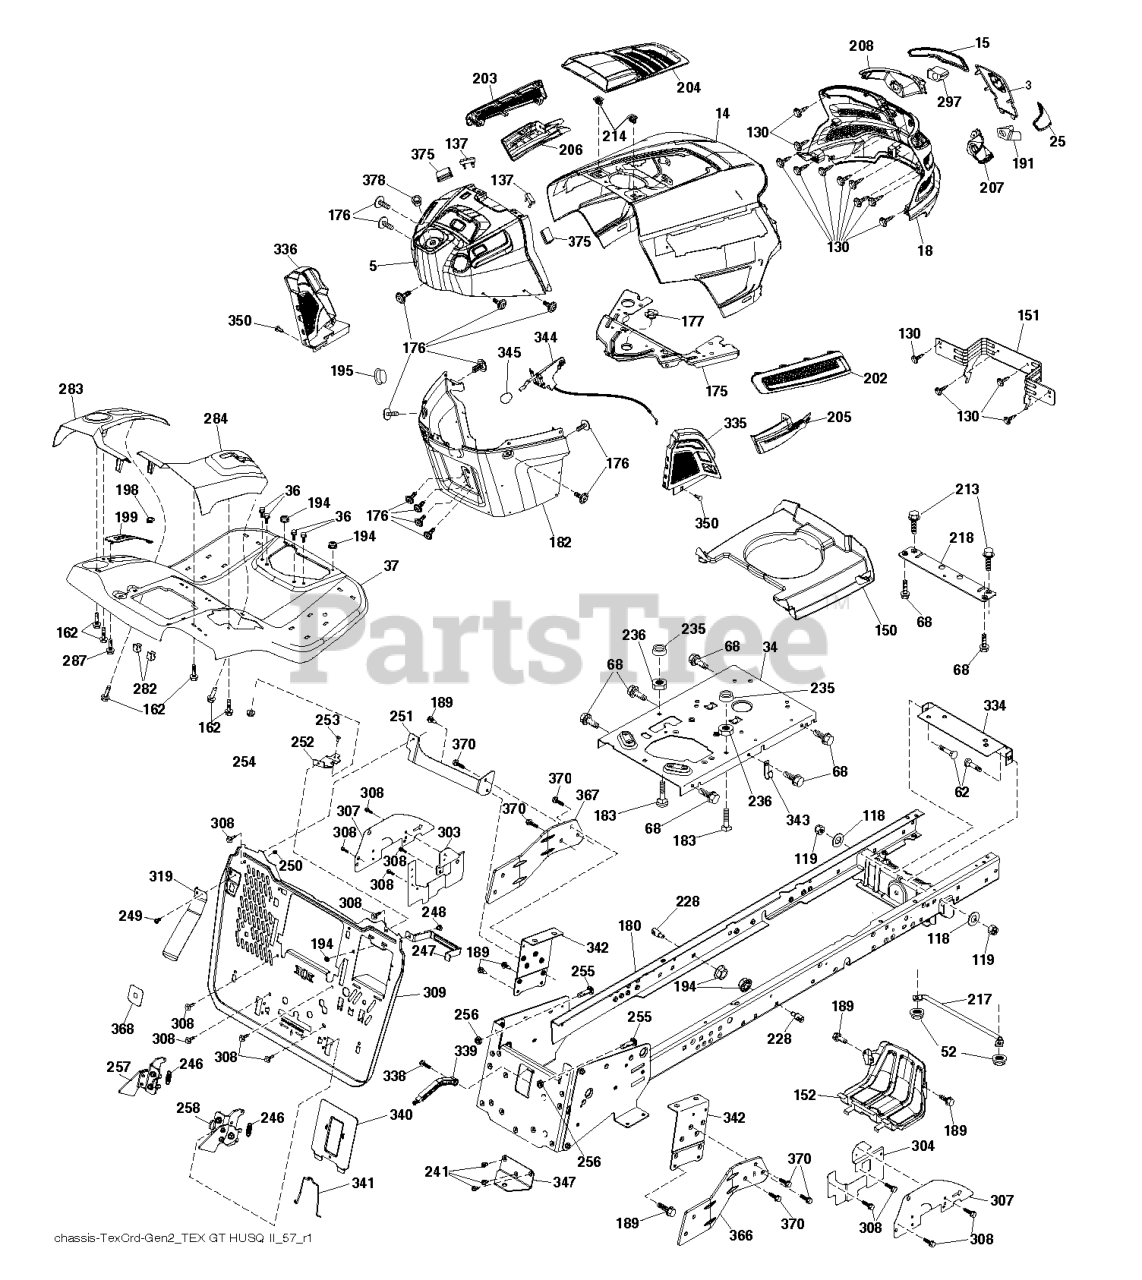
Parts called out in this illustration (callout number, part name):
3	APPLIQUE.SUBASM.GT.HUSQ.II
14	HOOD.ASM.HUSQVARNA.GT.TEX.ORAN
15	LENS.HEADLIGHT.LH.GTII.2011
18	GRILLE SUBASM.GT.II.LOW.HDLGHT
25	LENS.HEADLIGHT.RH.GTII.2011
34	PLATE.ENGINE.10GA.CRD.GENII
36	SCREW 5/16"
37	FENDER.TEX.SRD.CRD.FRN.GUARDS
52	LOCKNUT
62	BOLT D
68	SCR 5/16-18 X 1/2 SELFTAP ZN
118	WASHER
130	SCREW.#10 X 0.750.BOS
137	BUMPER DASH
150	AIR.DUCT.GTV.BLACK
151	BRACKET.PIVOT.HOOD.GT.HUSQ.II
152	SHIELD.BROWNING.PNT.GT.V2
162	SCREW.HI-LO.CONSOLE
175	PLATE.PNT.CROSSMEMBER.HUSQ/PRE
176	SCREW.#10-24X5/8.RN.QU
177	BUSHING STEERING
180	CHASSIS WELDMENT.CRD2.BKP_BLTS
182	DASH.LOWER.HUSQPREDGT.-CR.+EZM
183	BOLT.5/16-18X1-1/4 FULL THD
189	SCREW
191	INSERT.REFLECTIVE.RH.HUSQ.GTII
194	NUT LOCK HEX FLANGE 5/16-18
195	PLUG.HOLE.DASH.LOWER.12V.BLK
198	INDICATOR.DECK.LIFT.RED
199	PLATE DECK LIFT
202	VENT.SIDE.RH.GT.HUSQ.II.
203	VENT.SIDE.LH.GT.HUSQ.II.498
204	VENT.TOP.HUSQ.GT2
205	SIDE.TRIM.RH.GT.HUSQ.II
206	SIDE.TRIM.LH.GT.HUSQ.II.GRAY
207	HEADLIGHT.CUP.BEZEL.HUS.GT2.RH
208	HEADLIGHT.CUP.BEZEL.HUS.GT2.LH
213	HCS 5/16C X 3/4
214	CLIP.RETAINER.TINNER.
217	ROD.PIVOT.HOOD
218	X-PIECE.HOOD.STOP.NON/
228	STUD.FASTNER.W/ANTI-ROTATE
235	SPACER FENDER
236	NUT.CENTERLOCK.5/16-
241	SCREW 5/16-18X1
246	SPRING.LTCH.BGR.GEN2.5.CRD.TEX
247	STRAP.BATTERY.TCRD.GEN2.5X431
248	BOLT.CARR.5/16-18X1/2
249	SCREW.BUTTONHD.10-24X1/2.(2 2)
250	NUT 10-24 NYLOC
251	BRACKET.PNT.LH.SUPP.BKPLT.EDIP
252	BRACKET.PNT.RH.SUPP.BKPLT.EDIP
253	1/4-20X3/4 CARR BLT
254	NUT T
255	BOLT CROSS DRILLED CUP HEAD SQ
256	NUT.HEX.3/8-16
257	LATCH.ASM.BGR.LH.GEN2.5.STMPD
258	LATCH.ASM.BGR.RH.GEN2.5.STMPD
282	CLIP.RETAINER.CONSOLE.LT.HUSQ
283	CONSOLE.DECKLIFT.CRDII.498
284	CONSOLE.PEDAL.HYDRO
287	SCREW 1/4X20
297	INSERT.REFLECTIVE.LH.HUSQ.GTII
303	SHIELD.LWR.LH.30DECK/CRD1&2
304	SHIELD.LWR.RH.30DECK/CRD2PEDAL
307	SHIELD.UPPER.CRD.SRD.ISO
308	BOLT.5/16-18UNCX3/4 W/SEMS.BLK
309	BACKPLATE.TEXCRD2.5.BAGGER.479
319	LEVER.PRSNC.BGR.TEX.CRD.GEN2.1
334	BRACKET.ENGINE
335	COVER.LOWER.DASH.RH.BLACK
336	COVER-LH.LOWER.DASH.GT2.BLACK
338	BOLT BOLT SHOULDER
339	LEVER LEVER BAGGER
340	BATTERY.DOOR.TCRD.GEN2.5.MS479
341	LATCH.BATTERY.DOOR.TCRD
342	SUPPORT.PNT.FENDER.CRD.TEX
343	CLIP CLIP
344	CONTROL.EZ.MULCH.TEX/CRD
345	RP KNOB.OVAL.TAPERED.3/8-16BLK
347	HITCH HITCH TOW TEX CRD GEN 2
350	CLIP.X-MAS.TREE
366	BRACKET.RH.FRONT.BAGGER.BLACK
367	BRACKET.LH.FRONT.BAGGER.BLACK
368	FULL.LEVER.BAGGER.TEX.CRD
370	SCREW 3/8-16X1
375	BUMPER CLIP-ON. DASH 1"
378	BUSHING FLANGE; PLASTIC
